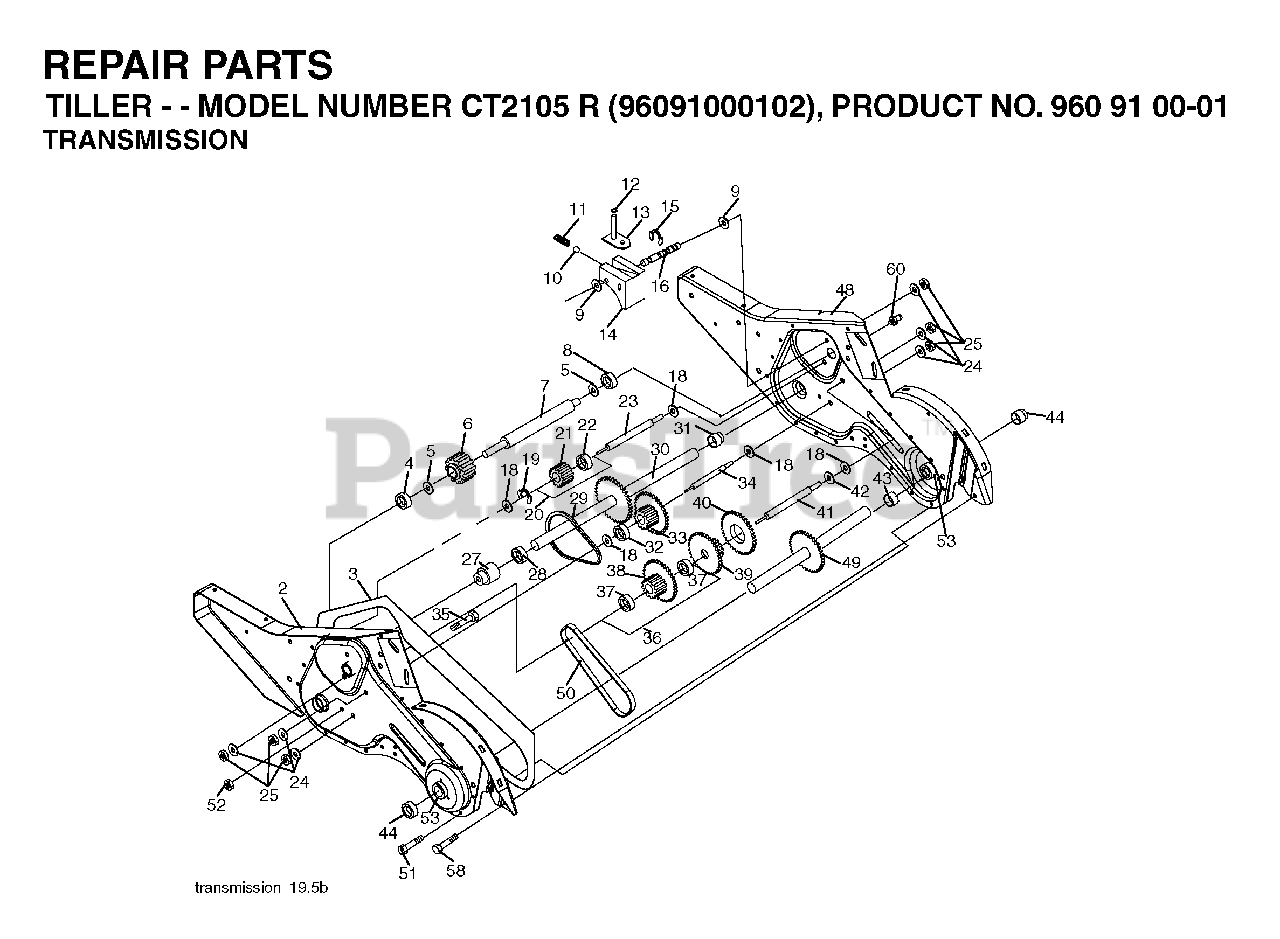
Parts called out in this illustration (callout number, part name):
1	TRANSMISSION ASM.
2	GEARCASE.ASM.CRT.LH.W/BEARING
3	GASKET
4	NEEDLE BRNG LT
5	THRUST WASHER
6	GEAR.PINION.INPUT
7	SHAFT.INPUT."D".TILLER
8	BEARING TI
9	WASHER, SEAL
10	STEEL BALL KIT
11	SPRING-SHIFT CRT
12	O-RING TI
13	SHIFTING ARM
14	SHIFT FORK TI
15	KLIP RING
16	SHAFT.SHIFTER.TILLER
19	KLIP RING
20	GEAR ASSY CRT
21	GEAR-REV IDLR CRT
22	NEEDLE BEARING TI
23	SHAFT CRT
24	LOCKWASHER
27	BEARING, SHAFT LH CRT
29	CHAIN CRT
30	GROUND SHAFT ASS'Y
31	BEARING, SHAFT RH CRT
32	SPACER TI
33	SPRCKT 8 GEAR CRT
34	SHAFT.SECONDARY.REDUCTION.CRT
35	SCRW WHIZ LOK CRT
36	SPROCKET ASS'Y W/BRG
37	BEARING
38	SPROCKET, TINE
39	GEAR TI
41	SHAFT.REDUCTION.TILLER
42	BRNG RACE T
43	SPACER TI
44	SEAL ASM, OIL
48	GEARCASE.ASM.CRT.RH.W/BEARING
49	TINE SHAFT
50	CHAIN.TILLER
51	SCREW
53	BEARING KIT
58	BOLT SHOULDER 1/4-20 UNC X.875
60	FITTING.GREASE.TAPERED
